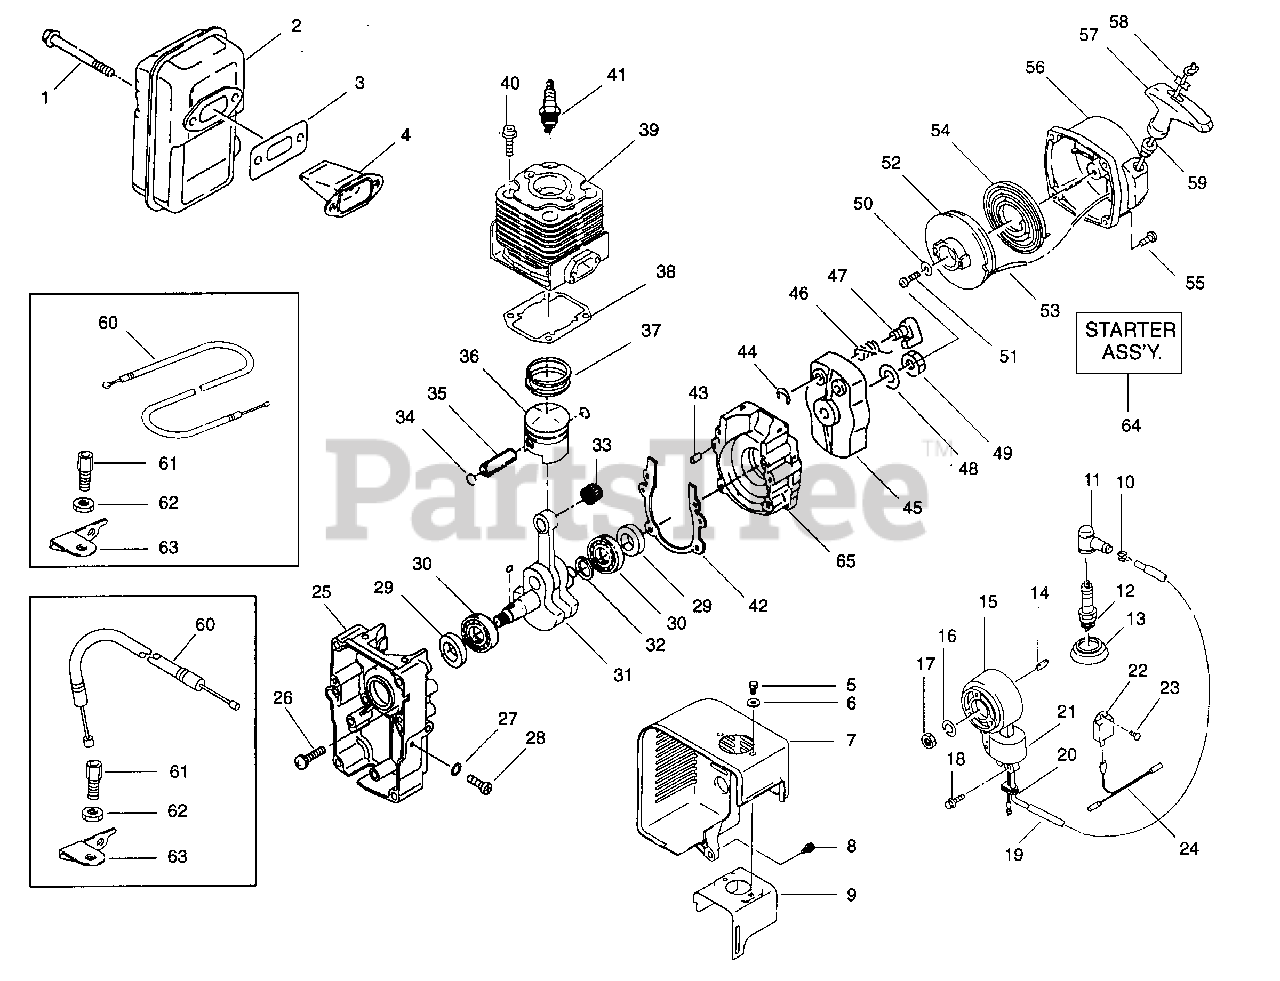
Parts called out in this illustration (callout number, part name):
2	Muffler
4	Spark Arrester
10	Terminal
12	Spark Plug
15	Flywheel
17	Nut
21	Ignition Coil Ass'y.
22	Igniter-Type 1 Only
23	Screw-Type 1 Only
24	Lead Wire
25	Crankcase - Drive Side
29	Oil Seal
31	Crankshaft Assy
32	Shim
33	Needle Bearing
34	Snap Ring
35	Piston Pin
37	Piston Ring Set
39	Cylinder
41	Spark Plug
45	Starter Pulley
46	Spring-Return
49	Nut
52	Recoil Starter
54	Spring - Recoil
55	Screw
56	Starter Case
59	Rope Guide
60	Cable-Throttle
61	Screw
62	Nut
64	Starter Ass'y.
65	Crankcase - Starter Side
